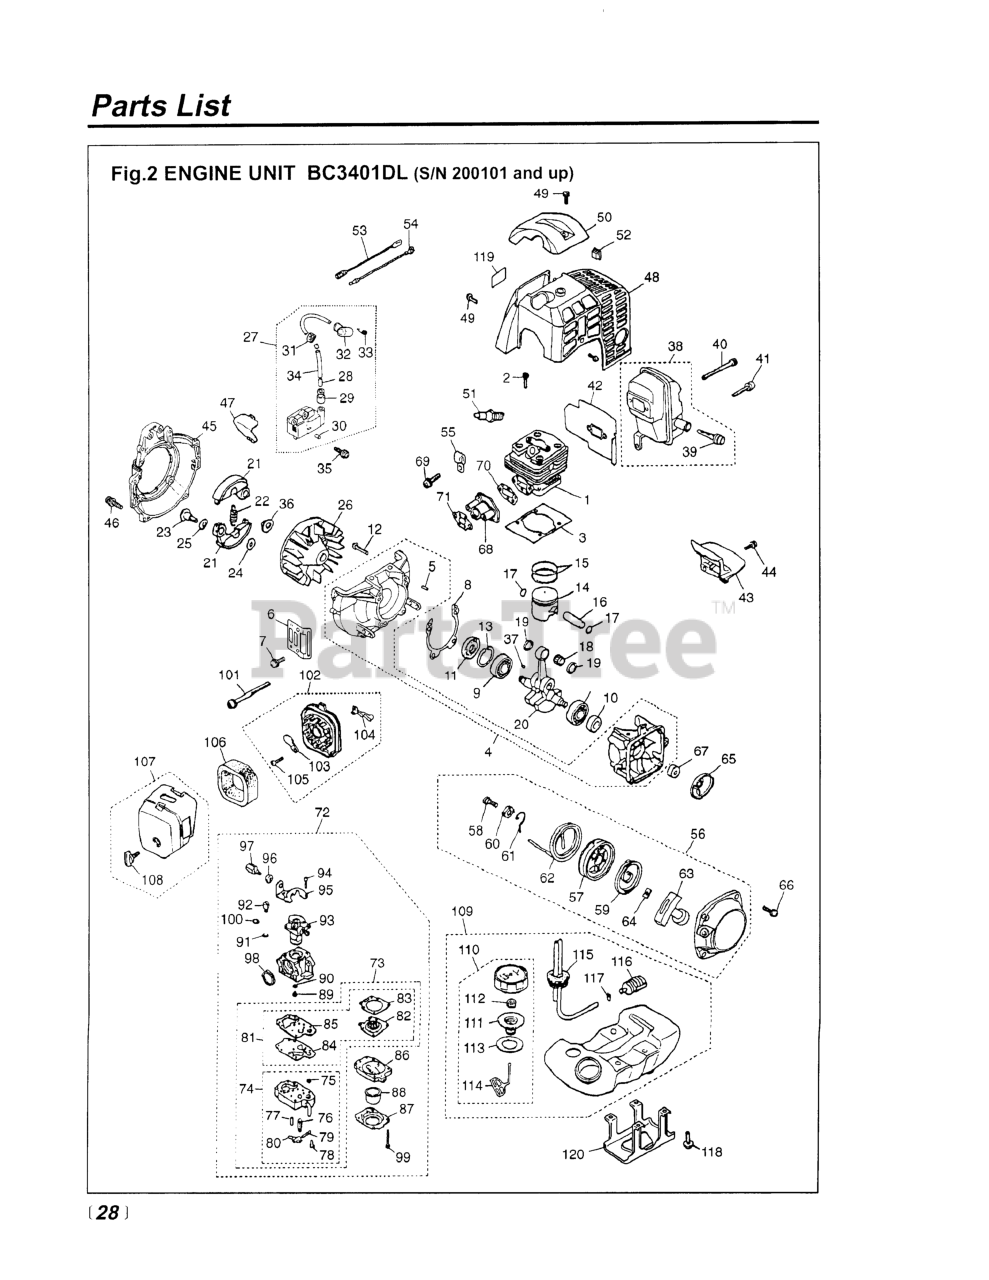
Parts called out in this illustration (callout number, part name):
1	CYLINDER
2	BOLT, M5 X 22
3	GASKET, BASE
4	CRANKCASE COMP (RPLS. -21100)
5	PIN
6	GUARD
7	SCREW,M5 X 14 (RPLS 1400-15510
8	GASKET
10	SEAL
11	SEAL, OIL (RPLS 1200-21220)
12	BOLT, M5 X 30
13	RING, SNAP, M32 x 1.2
14	PISTON
15	RING, PISTON
16	PIN, PISTON
17	RING, SNAP
18	BEARING
19	WASHER
20	CRANKSHAFT COMPL
21	SHOE, CLUTCH (RPLS -51110)
22	SPRING
23	SCREW
24	WASHER
25	WASHER (RPLS. -51240)
26	ROTOR
27	COIL ASSY.
28	CORD (RPLS 4700- )
30	PIN
31	GROMMET
32	CAP
33	SPRING
34	TUBE
35	BOLT, M4 x 20
37	KEY
38	MUFFLER ASSEMBLY
39	ARRESTER (RPLS 5850-15140)
40	BOLT, M5 x 60
41	BOLT (REPLACES 01252-30514)
42	GASKET, MUFFLER (RPLS -15210)
43	PLATE (RPLS-15220)
44	SCREW,M5 X 14 (RPLS 1400-15510
45	COVER
46	BOLT M5 x 20 (RPLS -12280)
48	COVER
49	SCREW M5 x 12
50	GUARD
53	CORD
54	CORD, EARTH
55	CLAMP
56	RECOIL ASSEMBLY
57	REEL
58	SCREW
59	SPRING, SPIRAL
60	COLLAR
61	ARM
62	ROPE (USE 4810-75160)
63	KNOB
64	PLATE, STOPPER
65	PULLEY
66	SCREW, M6 x 14
68	INSULATOR (REPLACES -13160)
69	SCREW
70	GASKET, INSULATOR
71	GASKET, CARBURETOR
72	CARBURETOR ASSY. (WYJ-319-1)
74	BODY, PUMP
75	SCREEN
76	VALVE, INLET
78	SCREW
79	PIN
80	LEVER
82	DIAPHRAGM
83	GASKET, DIAPHRAGM
84	DIAPHRAGM, PUMP
85	GASKET, PUMP
86	BODY, PURGE
87	COVER, PUMP
88	PUMP, PRIMING
89	JET 43.5
90	RING, O
91	RING
92	SWIVEL
93	VALVE ASSY
94	SCREW
96	NUT, CABLE ADJUSTER
97	SCREW, ADJUSTER
98	RING, PACKING
99	SCREW
100	WASHER
101	SCREW (RPLS 0263-30550)
102	BODY ASSY.
103	PLATE, CHOKE
104	LEVER, CHOKE
105	SCREW (REPLACES 50030272)
106	ELEMENT
107	COVER ASSY (REPLACES -82201)
108	KNOB (RPLS -82220)
109	TANK ASSY (RPLS 4700-85001)
110	CAP ASSY (RPLS -85201)
111	HOLDER (REPLACES -85230)
112	FILTER
113	PACKING
114	STOPPER
115	PIPE COMPLETE
116	FILTER ASSY
117	CLIP (REPLACES 2841-31280)
118	SCREW, M5 x 25
119	LABEL
120	TANK GUARD
